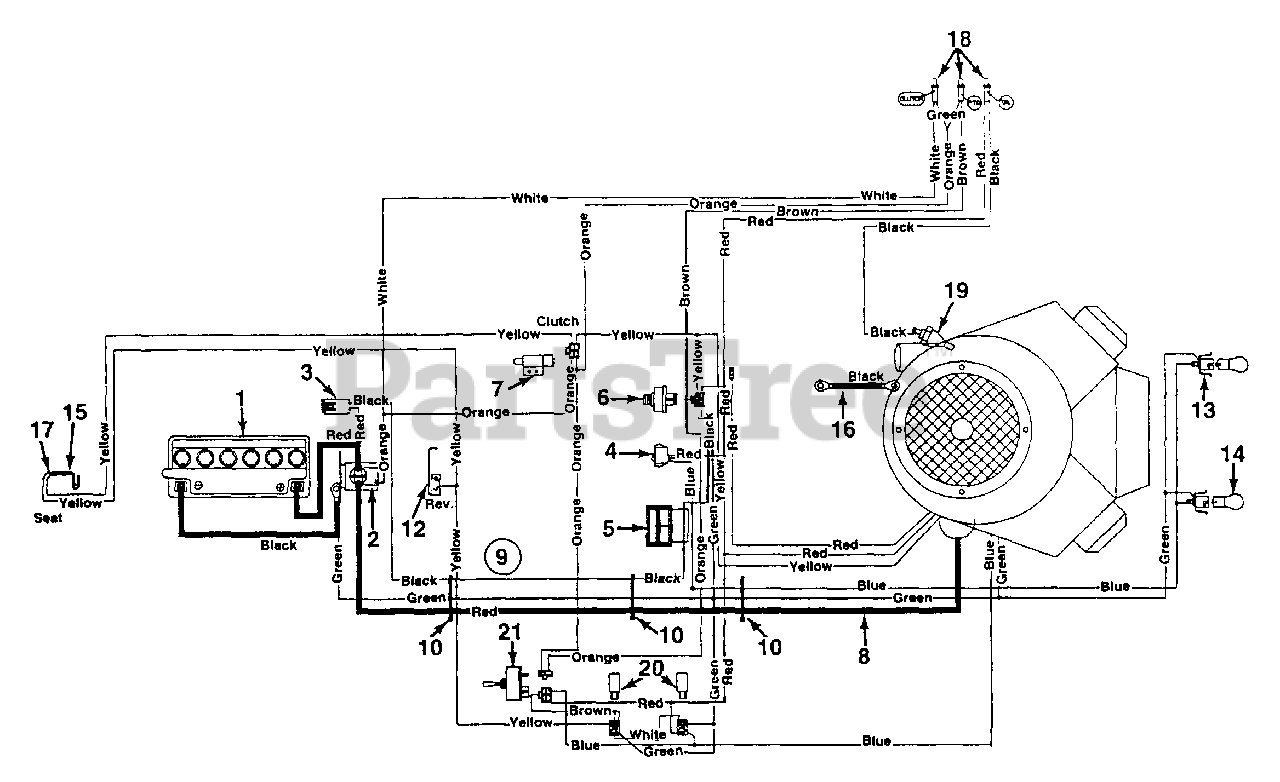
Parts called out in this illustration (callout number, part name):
1	Battery
2	Solenoid
3	Fuse 20 Amps
4	Light Switch
5	Ammeter
6	Ignition Switch
7	Safety Switch (Clutch)
8	Electric Wire 30" Lg.
9	Wire Harness
10	Cable Tie
12	Safety Switch (Reverse)
13	Socket
14	Bulb (Headlight)
15	Safety Switch (Seat)
16	Ground Wire 7.5" Lg.
17	Safety Switch (Seat)
18	Bulb
19	Oil Switch
20	Relay
21	PTO Switch
